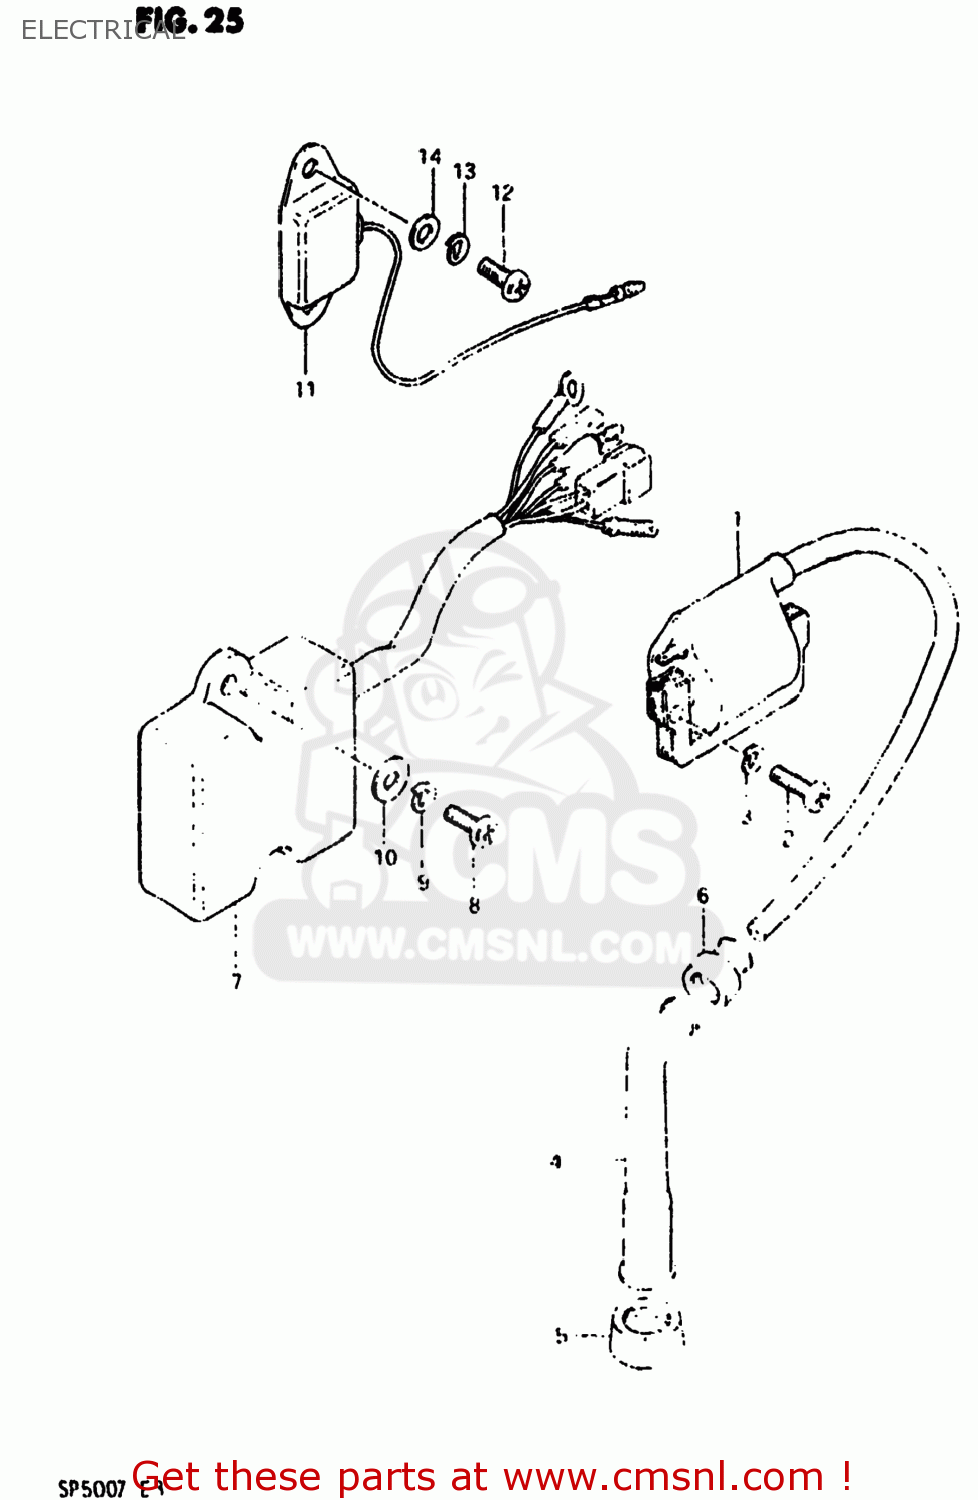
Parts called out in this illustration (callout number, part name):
1	COIL ASSEMBLY,IGNITION
2	BOLT
3	LOCK WASHER
4	CAP ASSY,SPARK PLUG
5	SEAL,SPARK PLUG
6	SEAL,SPARK PLU
7	CDI UNIT
8	SCREW
9	LOCK WASHER
10	WASHER (6.5X18X1.6)
11	REGULATOR ASSEMBLY,VOLTAGE
12	SCREW
13	LOCK WASHER
14	WASHER
